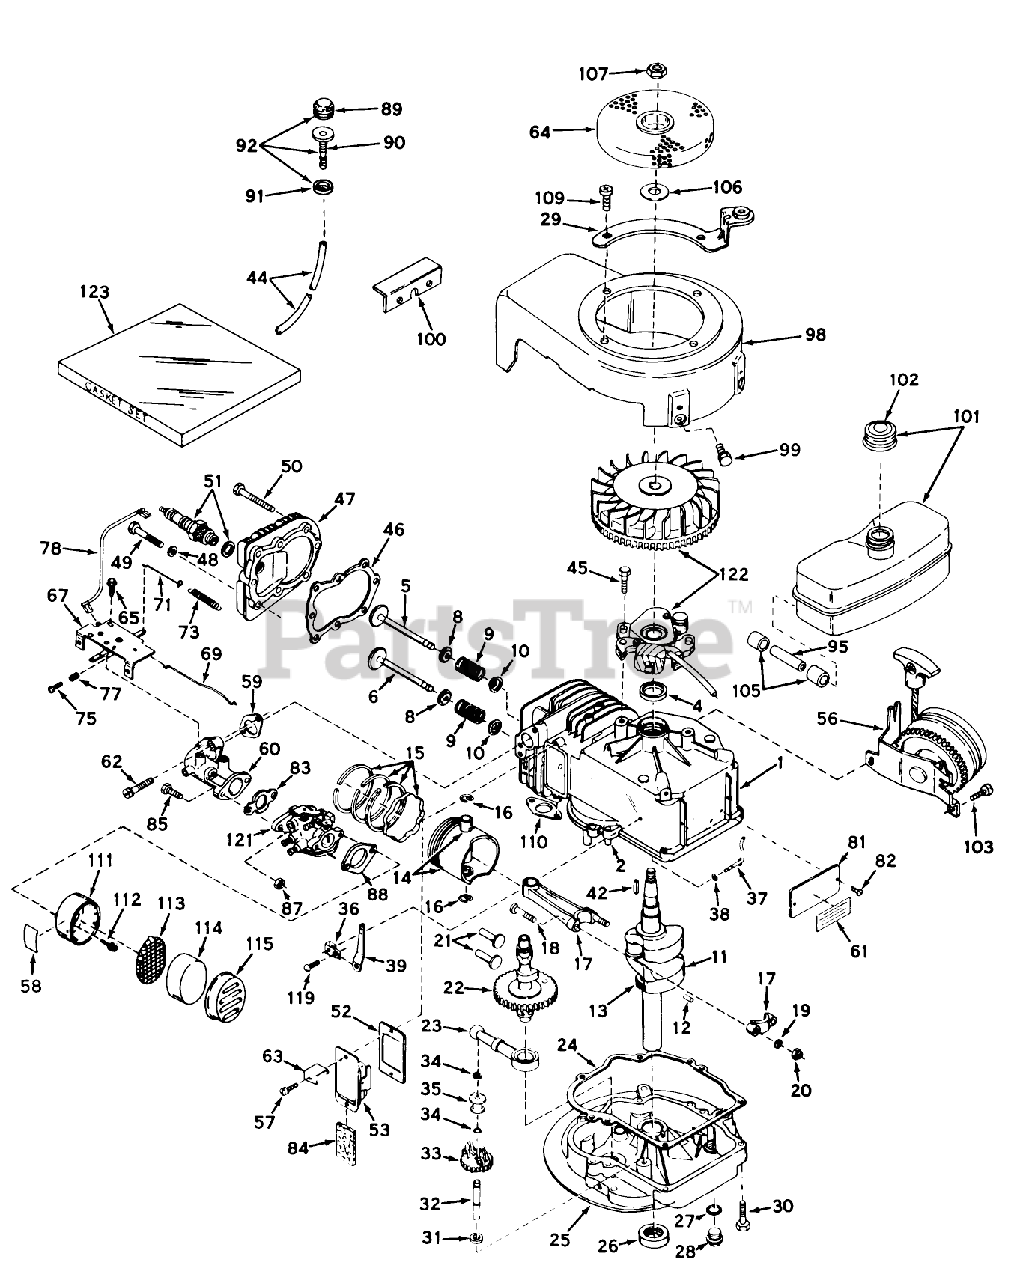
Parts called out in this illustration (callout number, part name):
1	Cylinder Assy. (Incl. Ref. 2 4)
2	Pin-Dowel
4	OIL SEAL
5	Valve, Intake (Incl. Ref. #38, 39 40) (Std.)
5	Valve, Intake(1/32"overs.)(Incl. Ref. 8, 9 10)
6	Valve, Exhaust (Standard)(Incl. Ref. 8, 9 10)
6	Valve, Exhaust (1/32" Overs.(Incl. Ref. 8, 9 10)
8	Cap-Upper Valve Spring
9	Spring-Valve
10	Cap-Valve, Spring
11	Crankshaft Assy. (Incl. Ref. Nos. 12 13)
12	Pin, Groove
13	Gear, Crankshaft
14	Piston Pin Assy. (Standard)(Incl. 2 of No. 16)
14	Piston Pin Assy. (.010 overs.)(Incl. 2 of Ref. 16)
14	Piston Pin Assy. (.020 overs.)(Incl. 2 of Ref. 16)
15	Ring Set, Piston (Std.)
15	Ring Set, Piston (.010 o.s.)
15	Ring Set, Piston (.020 o.s.)
16	Ring-Retaining, Piston Pin
17	Rod Assy., Connecting (Incl. Nos. 18, 19 20)
18	Bolt, Connecting
19	Washer
20	LOCKNUT
21	Lifter-Valve
22	Camshaft
23	Oil Pump ASM
24	Gasket, Mounting
25	Flange Assy., Mounting (Incl. Ref. 26, 27, 28 32)
26	Seal Oil
27	Gasket-Oil Drain
28	Plug Oil Drain
29	Bracket Assy., Starter
30	Screw (1/4-20 x 1-1/4)
31	Washer-Flat
32	Shaft-Governor
33	Governor Gear ASM
34	Ring-Retaining
35	Spool-Governor
36	Clamp-Lever, Governor
37	Rod, Governor (Incl. No. 36)
38	Washer-Flat
39	Lever, Governor
42	Key Flywheel
44	Line, Primer
45	Screw
46	Gasket-Cylinder Head
47	CYLINDER HEAD
48	Washer
49	Screw
50	Screw
51	SPARK PLUG
52	Gasket Breather
53	Breather Assembly (Incl. Nos. 52 84)
56	Starter, Side Mount Rewind
57	Screw
58	Decal, Air Cleaner
59	Gasket, Intake
60	Pipe, Intake
61	480B GIL SNWTHWR O/
62	Screw, Fil. Hd. Sems
63	Retainer Clip
64	Screen, Flywheel
65	Screw (10-24 x 9/16)
67	Control Assy., Speed
69	Link, Throttle to Governor
71	Link, Governor Spring
73	Spring, Governor
75	Screw
77	Spring-Compression
78	Wire, Ground
81	IDENTIFICATION PLATE
82	Stud
83	Gasket-Carburetor
84	Element-Breather
87	Nut and Lock Washer (1/4-28)
88	Gasket
89	Bulb, Primer
90	Body, Primer
91	Retainer, Primer Bulb
92	Primer Assy. (Incl. Nos. 89, 90 91)
95	Line, Fuel
98	Housing, Blower
99	Screw (1/4-20x19/32)
100	Bracket, Shroud
101	Tank, Fuel
102	Cap, Fuel Filler
103	Screw, Fil. Hd. Sems
105	Line-Fuel (8.62)
106	Washer
107	Hex Nut
109	Screw
110	Gasket Exhaust
111	Body, Air Cleaner
112	Screw (10-32 x 1/2)
113	Screen, Spacer
114	Element, Air Cleaner
115	Cover, Air Cleaner
119	Screw
120	Decal
121	Carburetor
122	Magneto
123	Gasket Set
